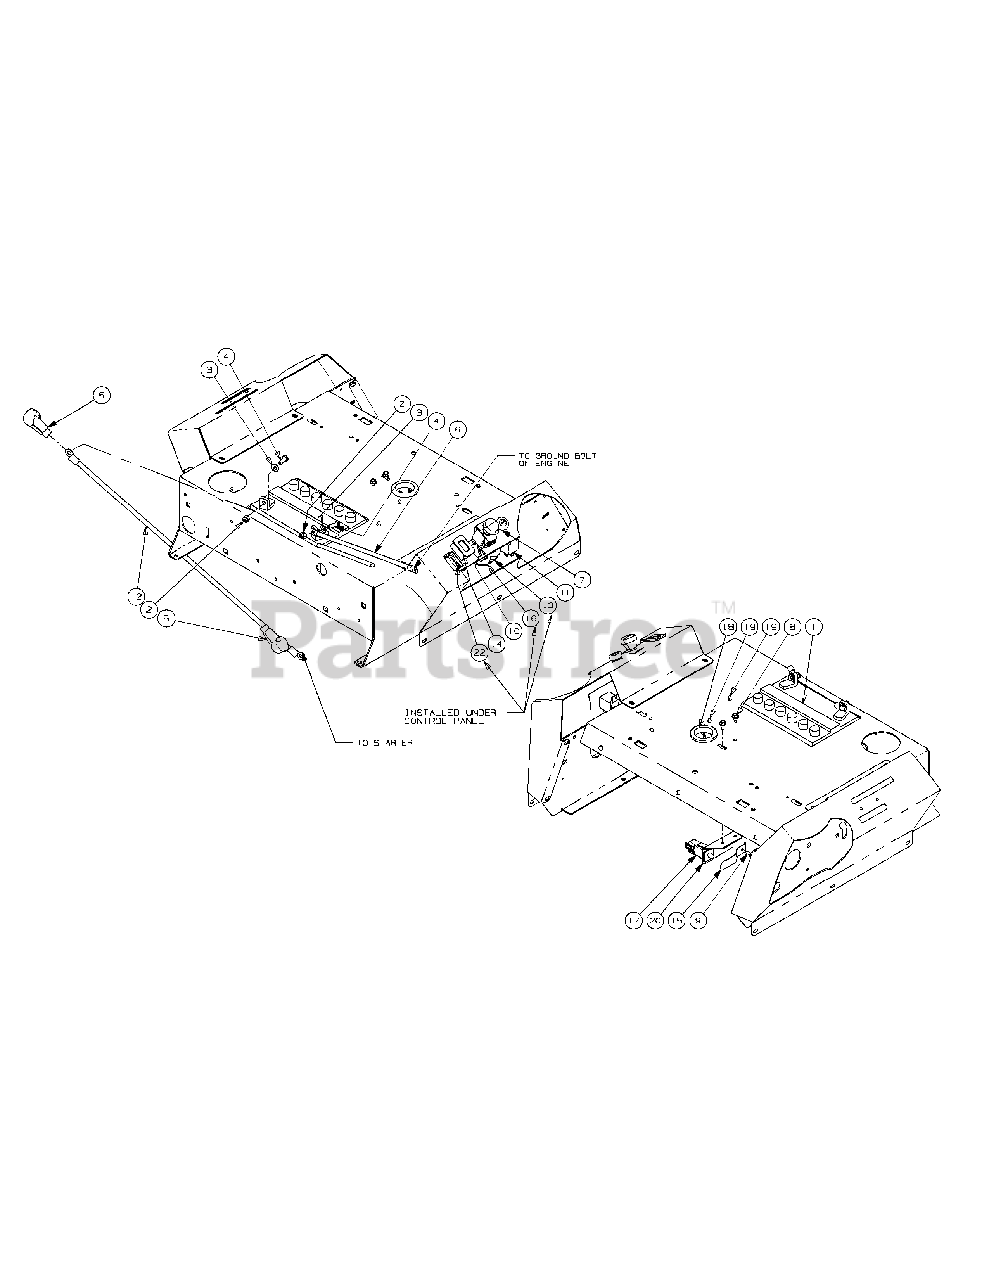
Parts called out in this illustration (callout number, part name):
1	Battery, 12V 225CCA 30Min
2	Lock Nut, Nylon Insert, 1/4-20
3	Flat Washer, 1/4
4	Hex Cap Screw, 1/4-20 x .75
5	Boot, 1" OD Rubber Battery-PST Red
6	Cable, Battery, Black, 17"
7	Nut, 5/8-32, w/Cap
8	Self Tapping Screw, 1/4-20 x 1/2
9	Self Tapping Screw, 10-32 x 1/2
10	Electric PTO Switch
11	Relay, 12V 40A
12	Cable, Battery, Red, 24"
13	Switch, Ignition, 6 Pin
14	Hour Meter includes:
15	Safety Switch Retainer Spring
16	PTO Switch Bracket
17	Switch, Safety N.O./N.C.
18	Gromment, 1.5 ID x 2.13 OD
19	Electrical Conduit Clip, 1/2
20	Brake Switch Mounting Bracket
